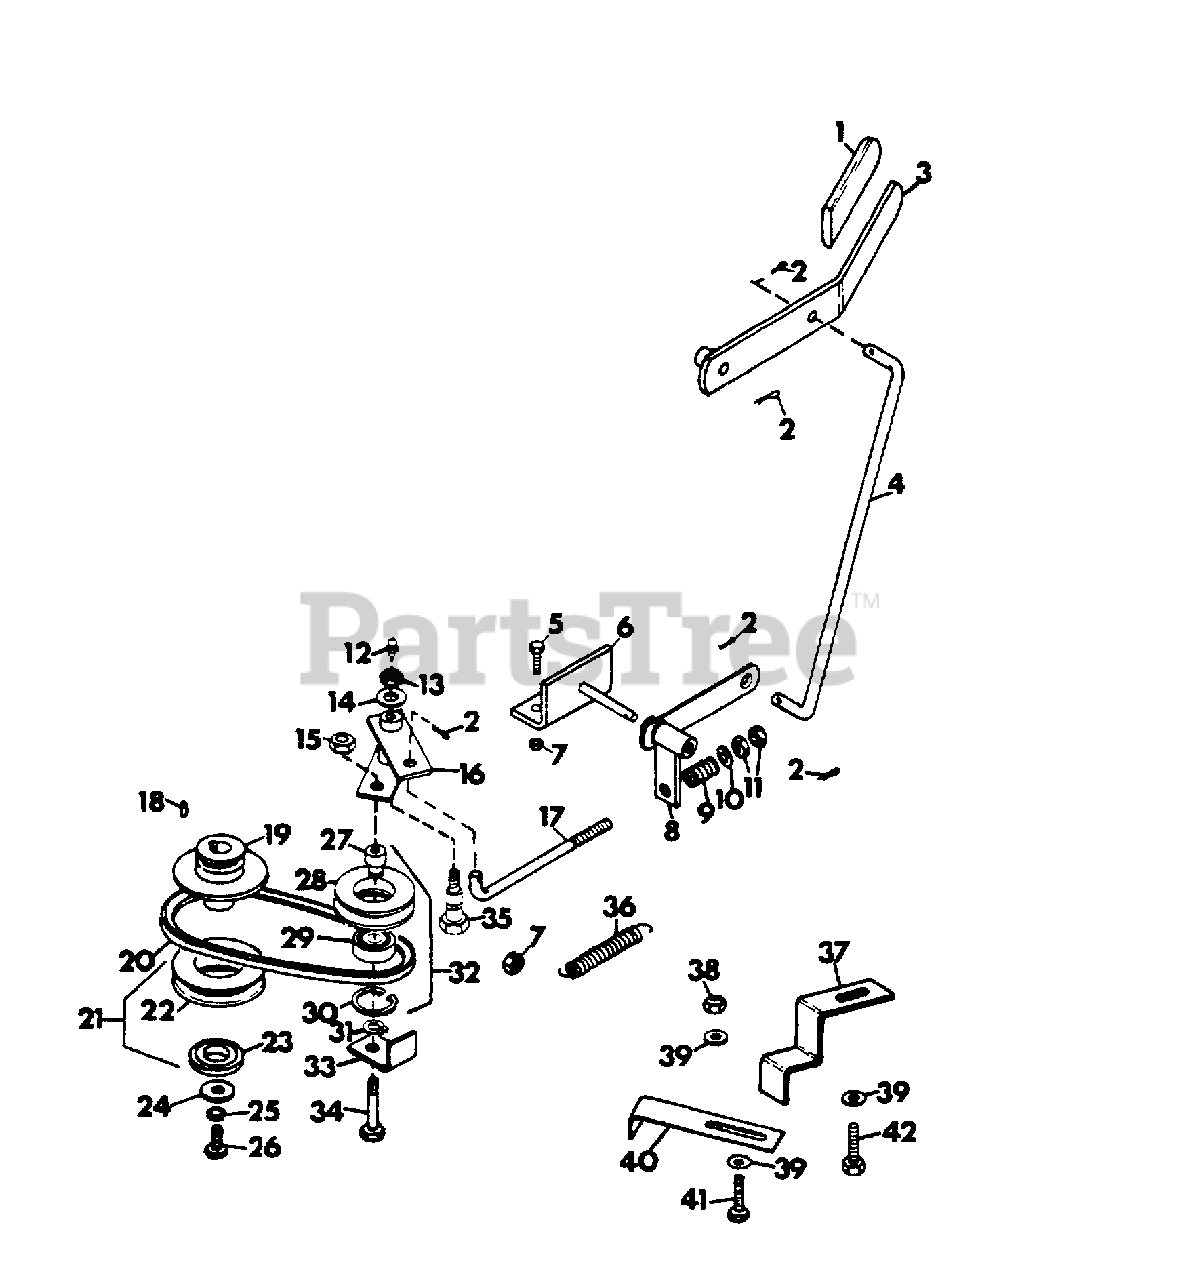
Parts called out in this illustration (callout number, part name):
1	GRIP, PTO LEVER
2	PIN, COTTER .09X.75
3	WELDMENT, PTO CONTROL
4	ROD, PTO CONTROL
5	BOLT, HEX 3/8-16X1.00
6	WELDMENT, PTO HANDLE LEVER
7	NUT, LOCK 3/8-16
8	WELDMENT, PTO CLUTCH LEVER
9	SPRING, COMPRESSION 1.0X.78
10	WASHER, FLAT .406X.812X.065
11	NUT, HEX 3/8-16
12	FITTING, LUBE 1/4-28
13	NUT, LOCK 1/2-13
14	WASHER, FLAT .531X1.062X.095
15	NUT, LOCK 1/2-13
16	WELDMENT, PTO ACTUATING
17	ROD, PTO CLUTCH ACTUATING
18	KEY, SQUARE .250X1.250
19	WELDMENT, CLUTCH HUB
20	BELT, VEE
21	ASSEMBLY, PTO CLUTCH
22	SHEAVE, MOWER CLUTCH
23	BEARING, BALL 1.574X3.149X.708
24	WASHER, SPECIAL FLAT
25	WASHER, LOCK 7/16 REG.
26	BOLT, HEX 7/16-20X2.00
27	BUSHING
28	SHEAVE, IDLER
29	BEARING, BALL
30	RING, RETAINING
31	RING, RETAINING
32	ASSEMBLY, IDLER SHEAVE
33	GUIDE, BELT
34	BOLT, HEX 1/2-13X2.50
35	BOLT, SHOULDER
36	SPRING, PTO RETURN
37	GUIDE, PTO V-BELT
38	NUT, LOCK 5/16-18
39	WASHER, FLAT .344X.688X.065
40	GUIDE, V-BELT
41	BOLT, HEX 5/16-18X.75
